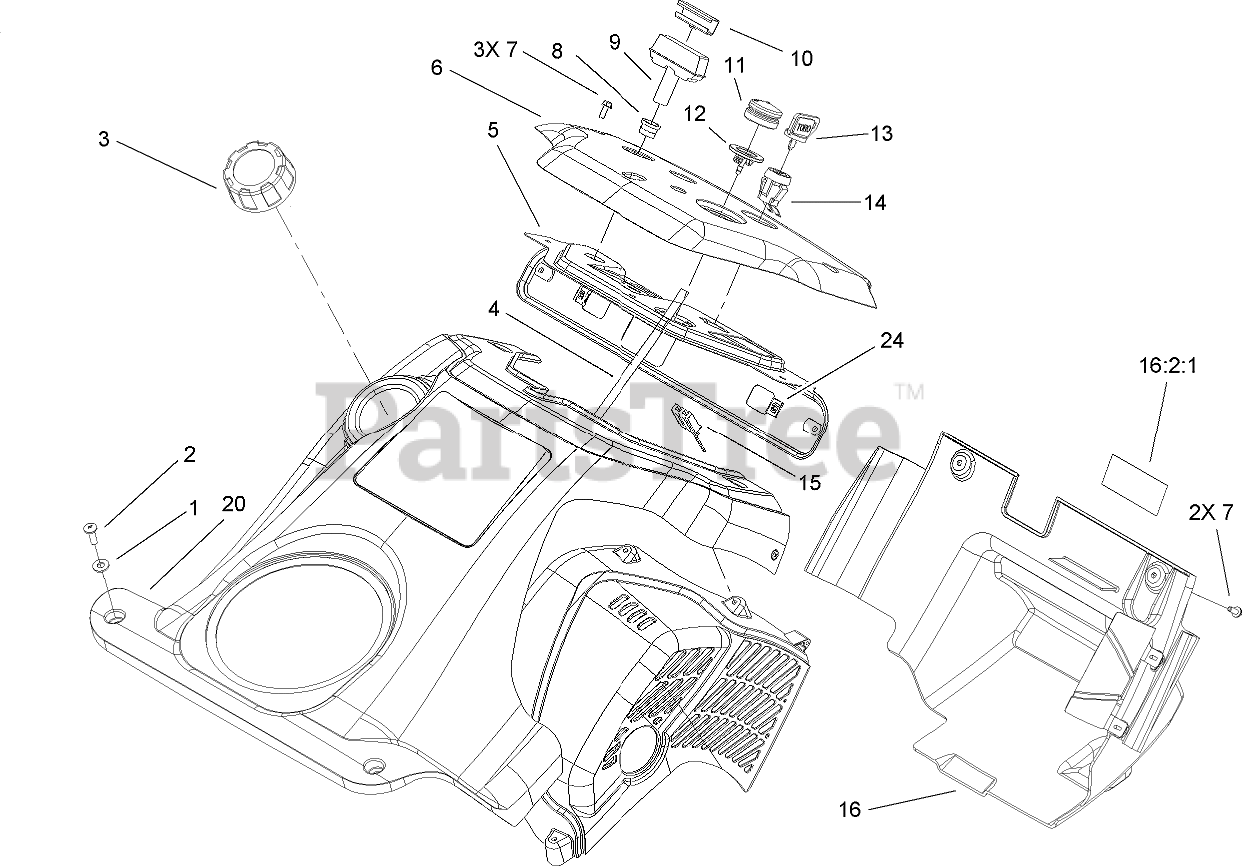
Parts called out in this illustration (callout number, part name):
1	WASHER-FLAT
2	SCREW-PPH
3	GAS CAP ASM
4	HOSE-PRIMER
5	PANEL-SUPPORT, CONTROL
6	PANEL-CONTROL
7	SCREW-HWH
8	GUIDE-ROPE, STARTER
9	HANDLE-START
10	CLIP-STARTER
11	BULB-PRIMER
12	BODY-PRIMER
13	KEY-IGNITION
14	SWITCH
15	CONNECTOR-BODY
16	LOWER SHROUD AND BAFFLE ASM
16:2	SHROUD-LOWER
16:2:1	DECAL
20	UPPER SHROUD ASM
24	NUT-SPEED
